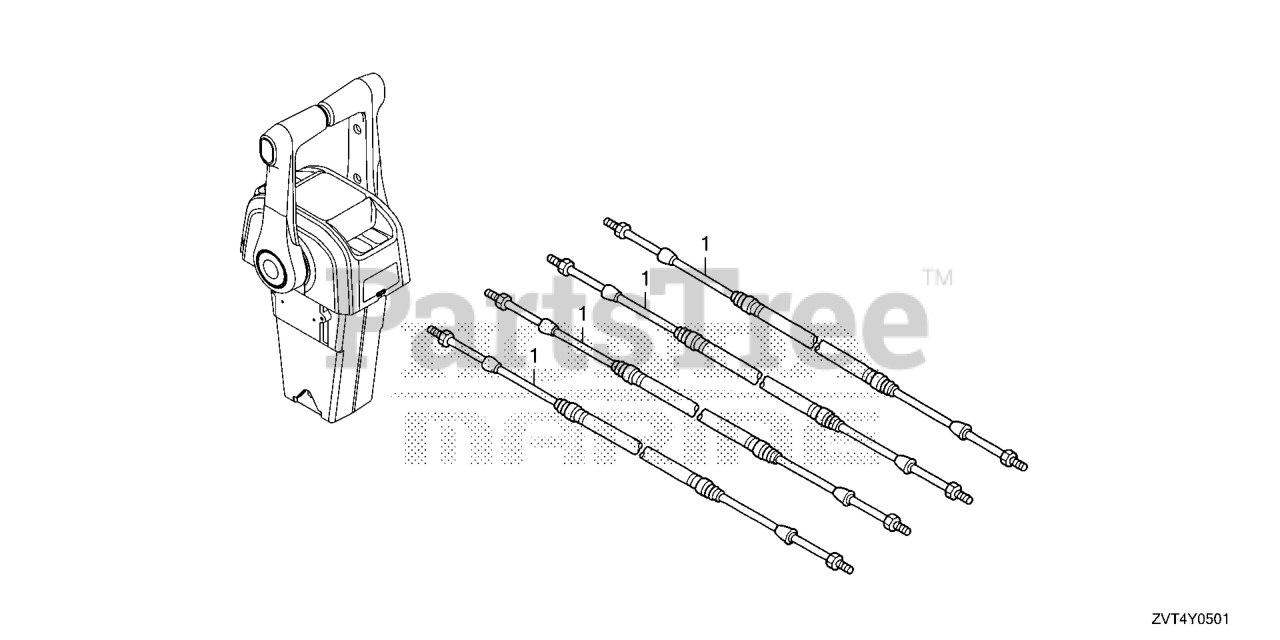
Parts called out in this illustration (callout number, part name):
1	CABLE, REMOTE CONTROL (5') (LOW FRICTION)
1	CABLE, REMOTE CONTROL (6') (LOW FRICTION)
1	CABLE, REMOTE CONTROL (7') (LOW FRICTION)
1	CABLE, REMOTE CONTROL (8') (LOW FRICTION)
1	CABLE, REMOTE CONTROL (9') (LOW FRICTION)
1	CABLE, REMOTE CONTROL (10'') (LOW FRICTION)
1	CABLE, REMOTE CONTROL (11'') (LOW FRICTION)
1	CABLE, REMOTE CONTROL (12'') (LOW FRICTION)
1	CABLE, REMOTE CONTROL (13'') (LOW FRICTION)
1	CABLE, REMOTE CONTROL (14'') (LOW FRICTION)
1	CABLE, REMOTE CONTROL (15'') (LOW FRICTION)
1	CABLE, REMOTE CONTROL (16'') (LOW FRICTION) (NOT AVAILABLE)
1	CABLE, REMOTE CONTROL (17'') (LOW FRICTION)
1	CABLE, REMOTE CONTROL (18') (LOW FRICTION) (NOT AVAILABLE)
1	CABLE, REMOTE CONTROL (1 9'') (LOW FRICTION)
1	CABLE, REMOTE CONTROL (20'') (LOW FRICTION) (NOT AVAILABLE)
1	CABLE, REMOTE CONTROL (21') (LOW FRICTION)
1	CABLE, REMOTE CONTROL (22') (LOW FRICTION) (NOT AVAILABLE)
1	CABLE, REMOTE CONTROL (2 3'') (LOW FRICTION)
1	CABLE, REMOTE CONTROL (24') (LOW FRICTION) (NOT AVAILABLE)
1	CABLE, REMOTE CONTROL (25') (LOW FRICTION)
1	CABLE, REMOTE CONTROL (26') (LOW FRICTION)
1	CABLE, REMOTE CONTROL (27') (LOW FRICTION)
1	CABLE, REMOTE CONTROL (28') (LOW FRICTION) (NOT AVAILABLE)
1	CABLE, REMOTE CONTROL (2 9') (LOW FRICTION)
1	CABLE, REMOTE CONTROL (30') (LOW FRICTION) (NOT AVAILABLE)
1	CABLE, REMOTE CONTROL (31') (LOW FRICTION)
1	CABLE, REMOTE CONTROL (32') (LOW FRICTION) (NOT AVAILABLE)
1	CABLE, REMOTE CONTROL (33') (LOW FRICTION)
1	CABLE, REMOTE CONTROL (34') (LOW FRICTION)
1	CABLE, REMOTE CONTROL (35') (LOW FRICTION)
